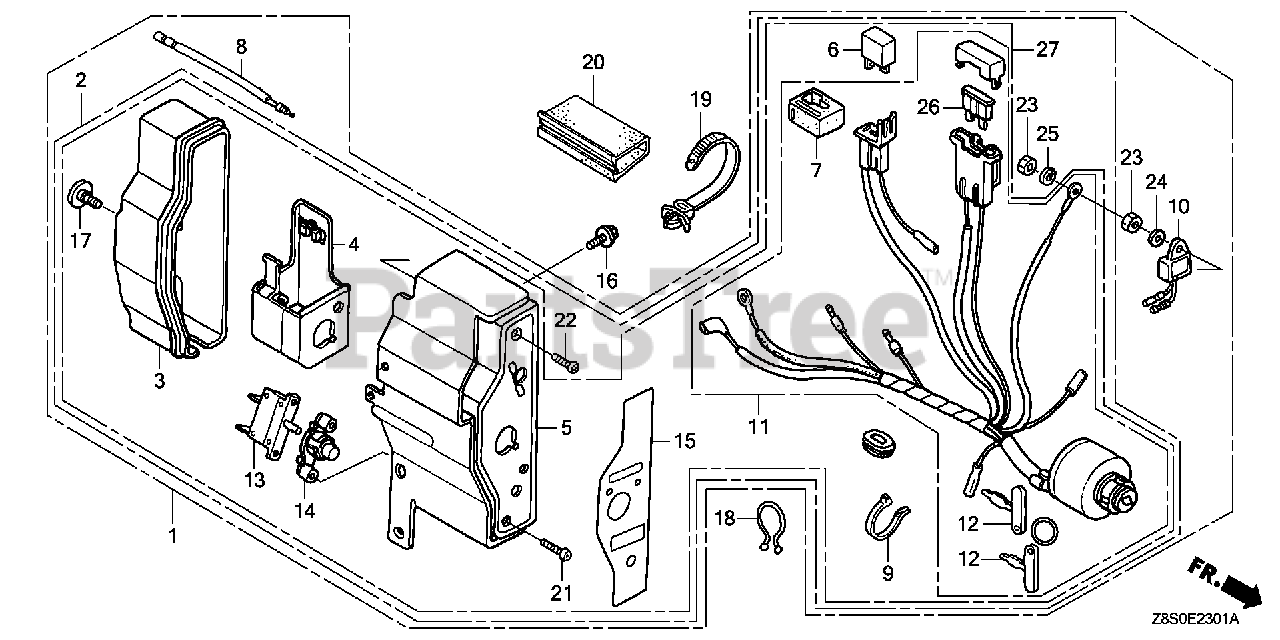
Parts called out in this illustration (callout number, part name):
1	BOX ASSY., CONTROL (3A) *NH1* (EXP-ALERT) (BLACK)
1	BOX ASSY., CONTROL (3A) *R280* (EXP-ALERT) (POWER RED)
3	CASE, CONTROL
4	BRACKET, CASE MOUNTING
5	PANEL, CONTROL *NH1* (BLACK)
5	PANEL, CONTROL *R280* (POWER RED)
6	RECTIFIER ASSY., SILICON (SHINDENGEN)
7	SUSPENSION, CONNECTOR
8	SUB-WIRE HARNESS
10	ALERT UNIT, OIL
11	SWITCH ASSY., COMBINATION (3A-CHARGE)
12	KEY (HONDALOCK)
13	PROTECTOR, CIRCUIT (3.5A)
14	LENS ASSY., PROTECTOR
15	MARK, CONTROL BOX (EXTERNAL)
16	BOLT, FLANGE (6X12) (CT200)
17	SCREW, SPECIAL (6X12)
18	CLIP, PURSE LOCK
19	STRAP, CABLE (118MM) (BLACK)
20	TUBE, FASTENER (30MM)
21	SCREW, PAN (3X12)
22	SCREW, PAN (4X12)
23	NUT, HEX. (4MM) (SOURCE: VINTAGE PARTS INC.)
24	WASHER, PLAIN (4MM)
25	WASHER, SPRING (4MM)
26	FUSE, BLADE (15A)
